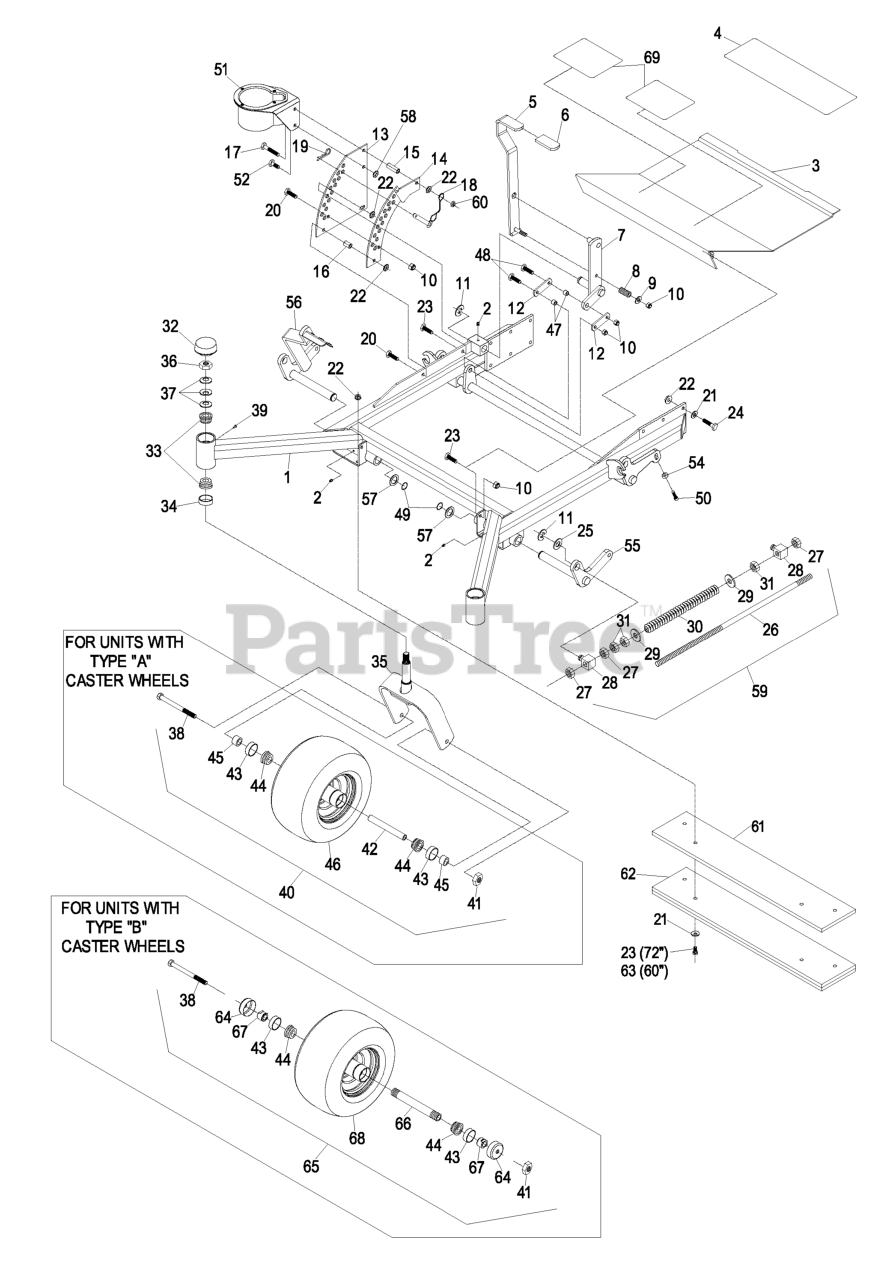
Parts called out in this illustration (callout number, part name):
2	FITTING-GREASE
3	ASM,FLOORPAN W/PADS
4	PAD-ANTISKID
5	LIFT LEVER/GRIP ASM
6	GRIP-LEVER, LIFT
7	ARM-LIFT, DECK
8	SPRING-COMPRESSION
9	WASHER-FLAT
10	NUT-LOCK, NI
11	RING-RETAINING, EXT
12	ARM-LIFT, DECK
13	PLATE-LIFT, DECK
14	PLATE-LIFT, DECK
15	BUSHING-LEVER, LIFT
16	BUSHING-LEVER, LIFT
17	SCREW-HH
18	PIN-HITCH (W/LANYARD)
19	PIN-COTTER
20	SCREW-HH
21	WASHER-BELLEVILLE
22	NUT-HHF, WHIZ
23	SCREW-HH
24	SCREW-HH
25	WASHER-FLAT
26	ROD-LIFT, DECK
27	NUT-HEX
28	SWIVEL-DECK MOUNT, REAR
29	WASHER-FLAT
30	SPRING-SUPPORT, DECK
31	NUT-JAM
32	CAP-GREASE
33	Cone-Bearing Tapered Roller
34	SEAL-GREASE
36	NUT-LOCK, NI
37	WASHER-BELLVILLE
38	SCREW-HH
41	NUT-LOCK, NI
42	SPACER-CASTER, FRONT
43	SEAL-CASTER
44	BEARING-CONE, TAPERED ROLLER
45	SPACER-BEARING
47	BUSHING
48	SCREW-HH
49	RING-RETAINING
50	SCREW-HSH
52	SCREW-HH
54	NUT-JAM
55	WLD, FRONT LIFT SHAFT - L
56	WLD, FRONT LIFT W/ LEVER
57	WASHER-SPACER
59	FRONT FRAME SPRING ASM
62	WEIGHT BAR ASM
63	SCREW-HH
64	GUARD-SEAL
67	SPACER-NUT
69	PAD-ANTI SKID
